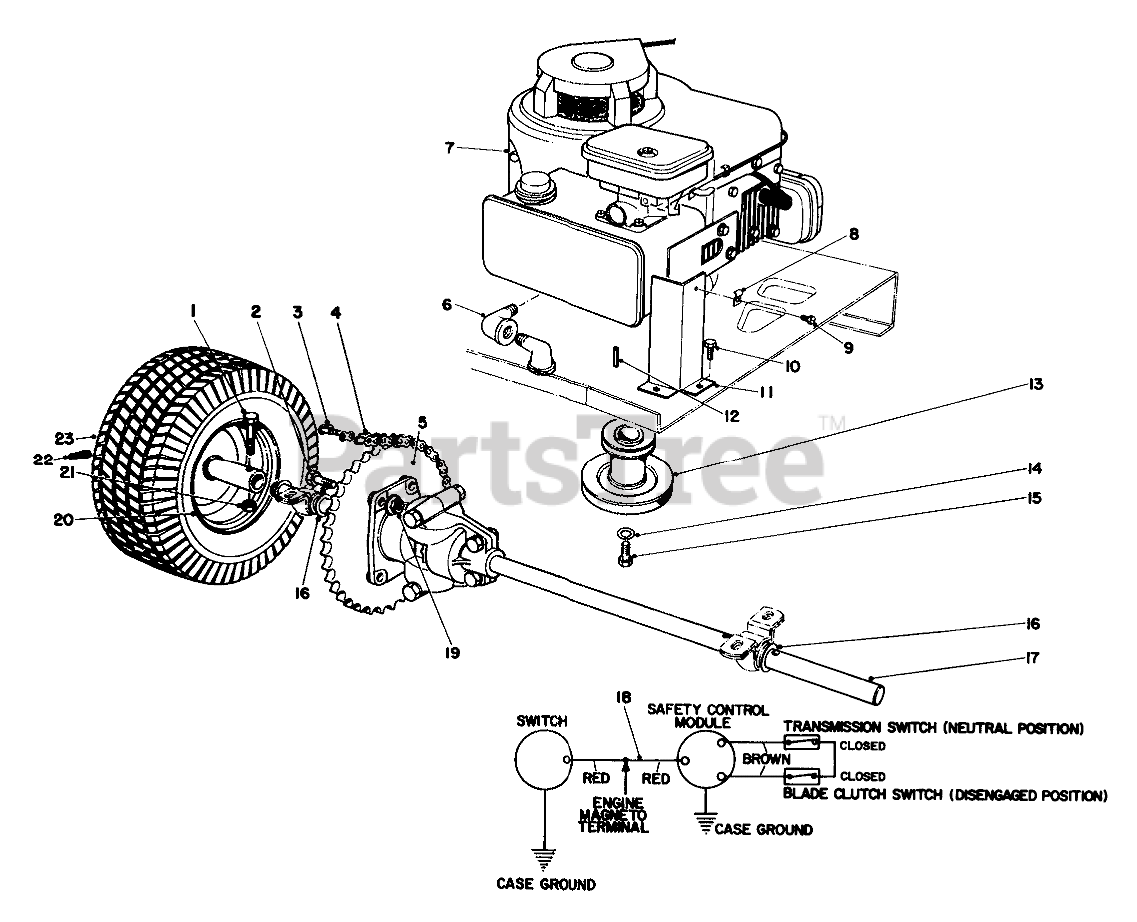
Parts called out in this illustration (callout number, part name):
1	SCREW-HH
2	SCREW-HH
3	LINK-CONNECTING
4	ROLLER CHAIN
5	Sprocket
6	ELBOW-STREET, 90 DEG
7	Engine
9	Screw
10	SCREW-HWHTF
11	Support Wire
13	ENGINE SHEAVE
14	WASHER-LOCK
15	SCREW-HH
16	WASHER
17	Differential
18	Wiring Harness
19	NUT-LOCK, CONE
21	NUT-LOCK, CONE
22	STEM-VALVE
23	Tire
